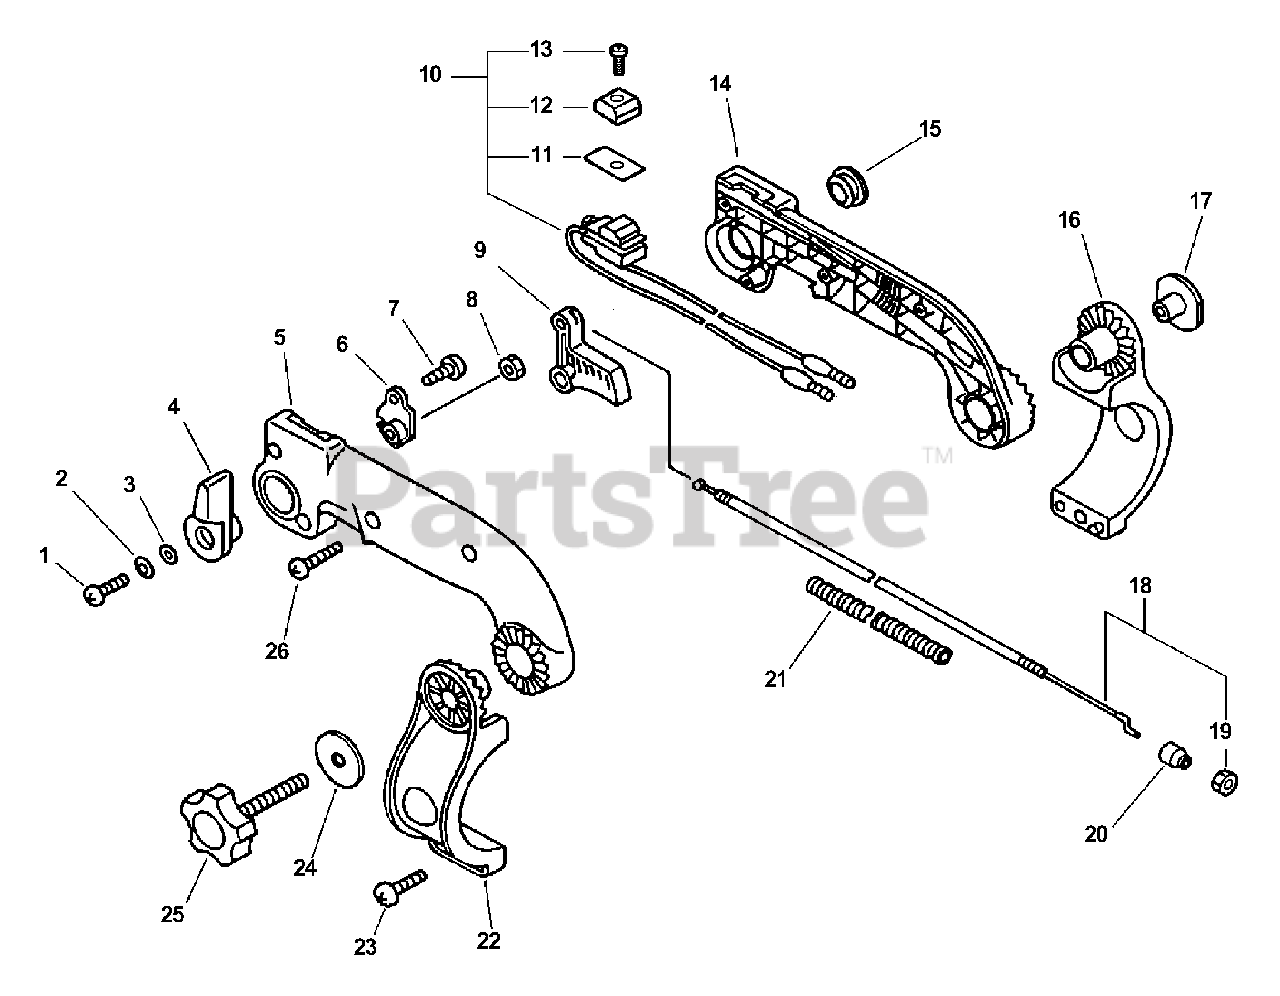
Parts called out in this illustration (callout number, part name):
1	SCREW 6×20
2	WASHER, SPRING 6
3	WASHER 6.5×13×1
4	CONTROL, THROTTLE
5	CONTROL HANDLE - LEFT
6	BRACKET, THROTTLE
7	SCREW 4×10
8	NUT, HEX M6
9	TRIGGER, THROTTLE
10	SWITCH, ON-OFF
11	LABEL, SWITCH
12	KNOB, SWITCH - ORANGE
13	SCREW 3×10
14	CONTROL HANDLE - RIGHT
16	BRACKET, HANDLE - RIGHT
18	CABLE, THROTTLE
19	NUT, HEX M6
20	CAP, DUST
21	TUBE, FLEXIBLE 7×790
22	BRACKET, HANDLE - LEFT
23	SCREW, TAPPING 5×20
25	KNOB, SCREW
26	SCREW 4×22
